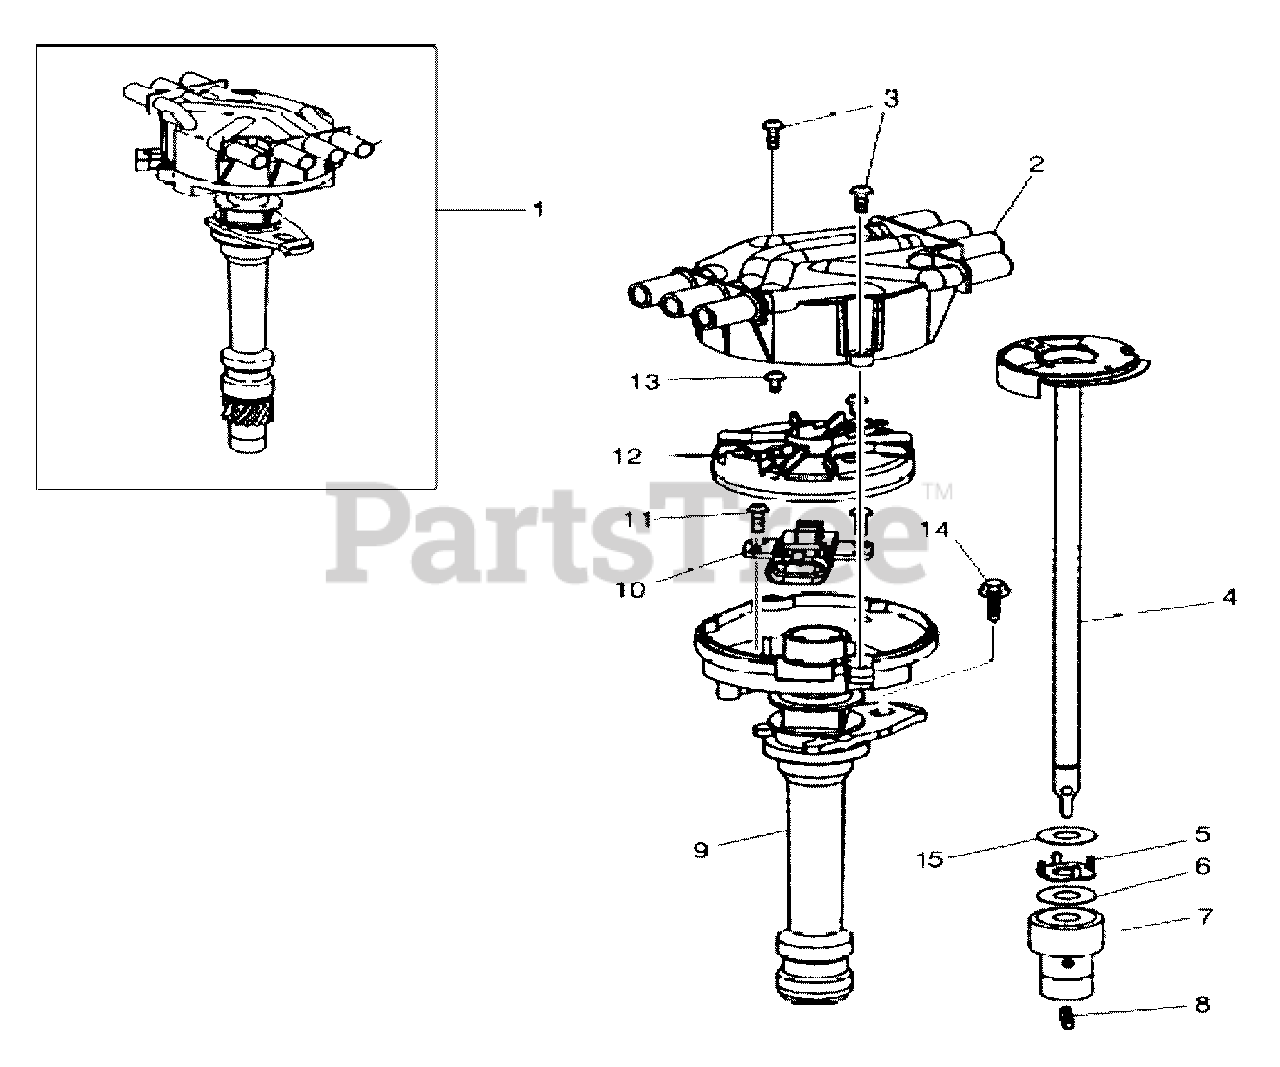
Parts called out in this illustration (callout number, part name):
1	DISTRIBUTOR
2	CAP, DISTRIBUTOR
3	BOLT
4	SHAFT
5	WASHER
6	WASHER
7	GEAR KIT
8	PIN
9	HOUSING
11	BOLT
12	ROTOR, DISTRIBUTOR
13	BOLT
14	BOLT
15	GASKET
